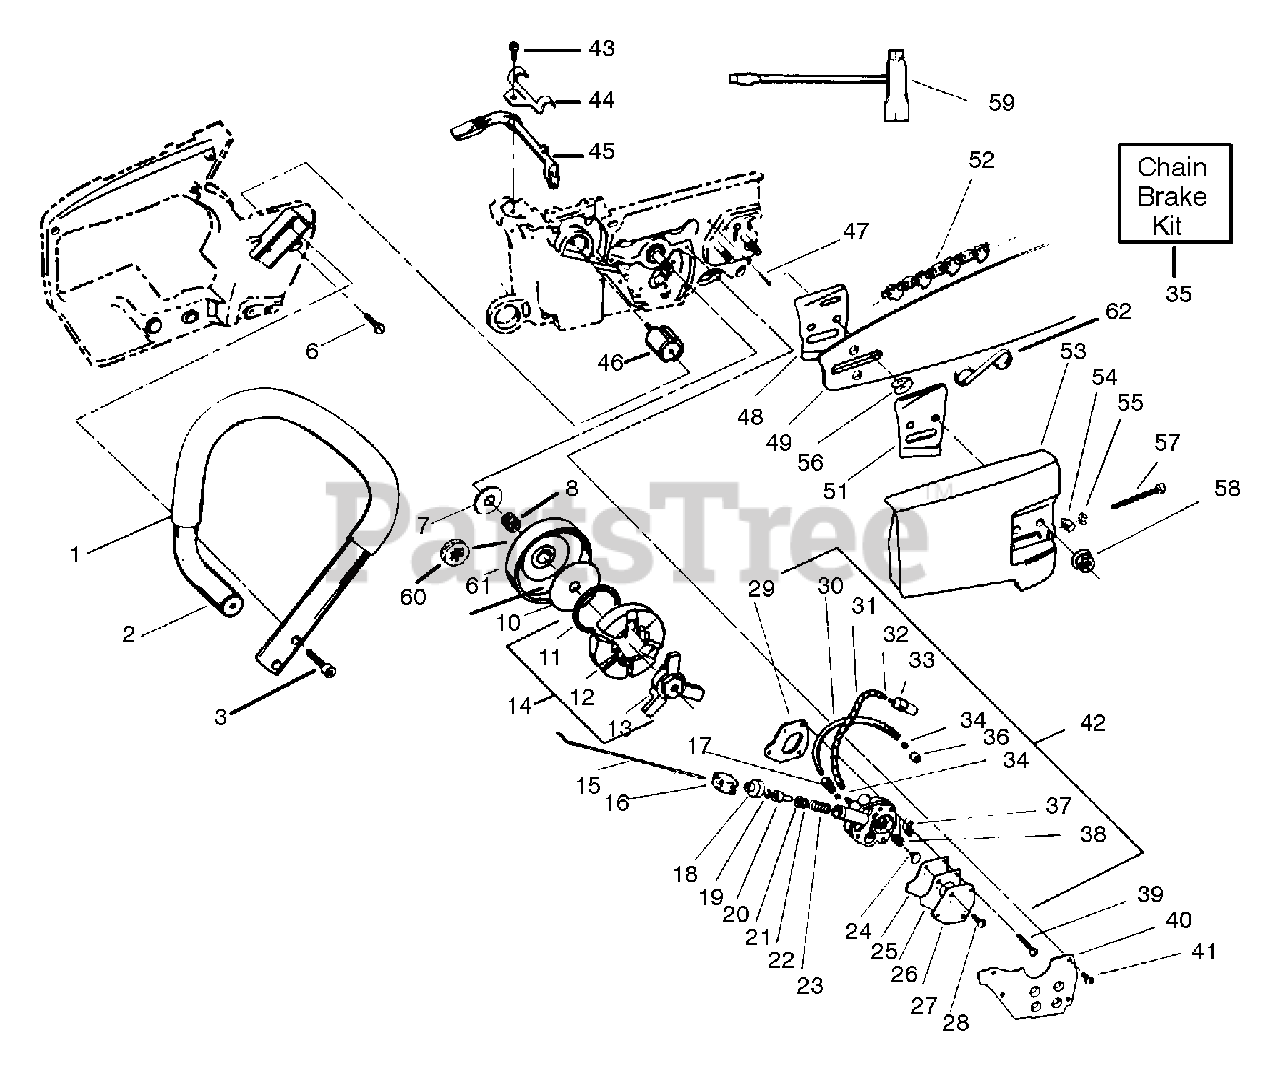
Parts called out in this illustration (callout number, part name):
1	Handlebar Grip Kit
2	Handlebar Ass'y.
7	Thrust Washer
8	Clutch Bearing
10	Plate Clutch
11	Clutch Spring
12	Clutch Shoe
13	Clutch Spider
14	Clutch Ass'y.
15	Manual Oiler Rod
16	Oiler Rod Boot
17	Tubing Nut
18	Oil Pump Cap
19	Retainer Ring
21	Quad Ring
24	Button & Pintle Ass'y.
25	Diaphragm
27	Pump Cover
30	Oil Line Dis-charge (Bulk 8115)
31	Oil Line Protector Spring
32	Oil Line (Bulk 8132)
32	Oil Line Pick-Up Ass'y.
33	Oil Line Pick-Up Weight
34	Sleeve-1/8 Tubing
35	Chain Brake Kit
37	Oil Pump Vent Foam
38	Diaphragm Spring
40	Oiler Cover Plate
42	Oil Pump Ass'y.Kit
44	Manual Oiler Lever
45	Side Isolator
46	Use on Guide Bar
46	Powerhead
46	Powerhead Oil Vent Replace-
47	ment Kit
48	Guide Bar Plate
49	Guide Bar
51	Guide Bar Plate-
53	Bar Clamp Ass'y.
54	Bar Adj. Pin
55	"E" Ring Adj. Screw
58	Nut
59	Scrench
60	Floating Rim
61	Drum & Sprocket Ass'y.
61	Drum for Sprocket
62	"S" Clip
